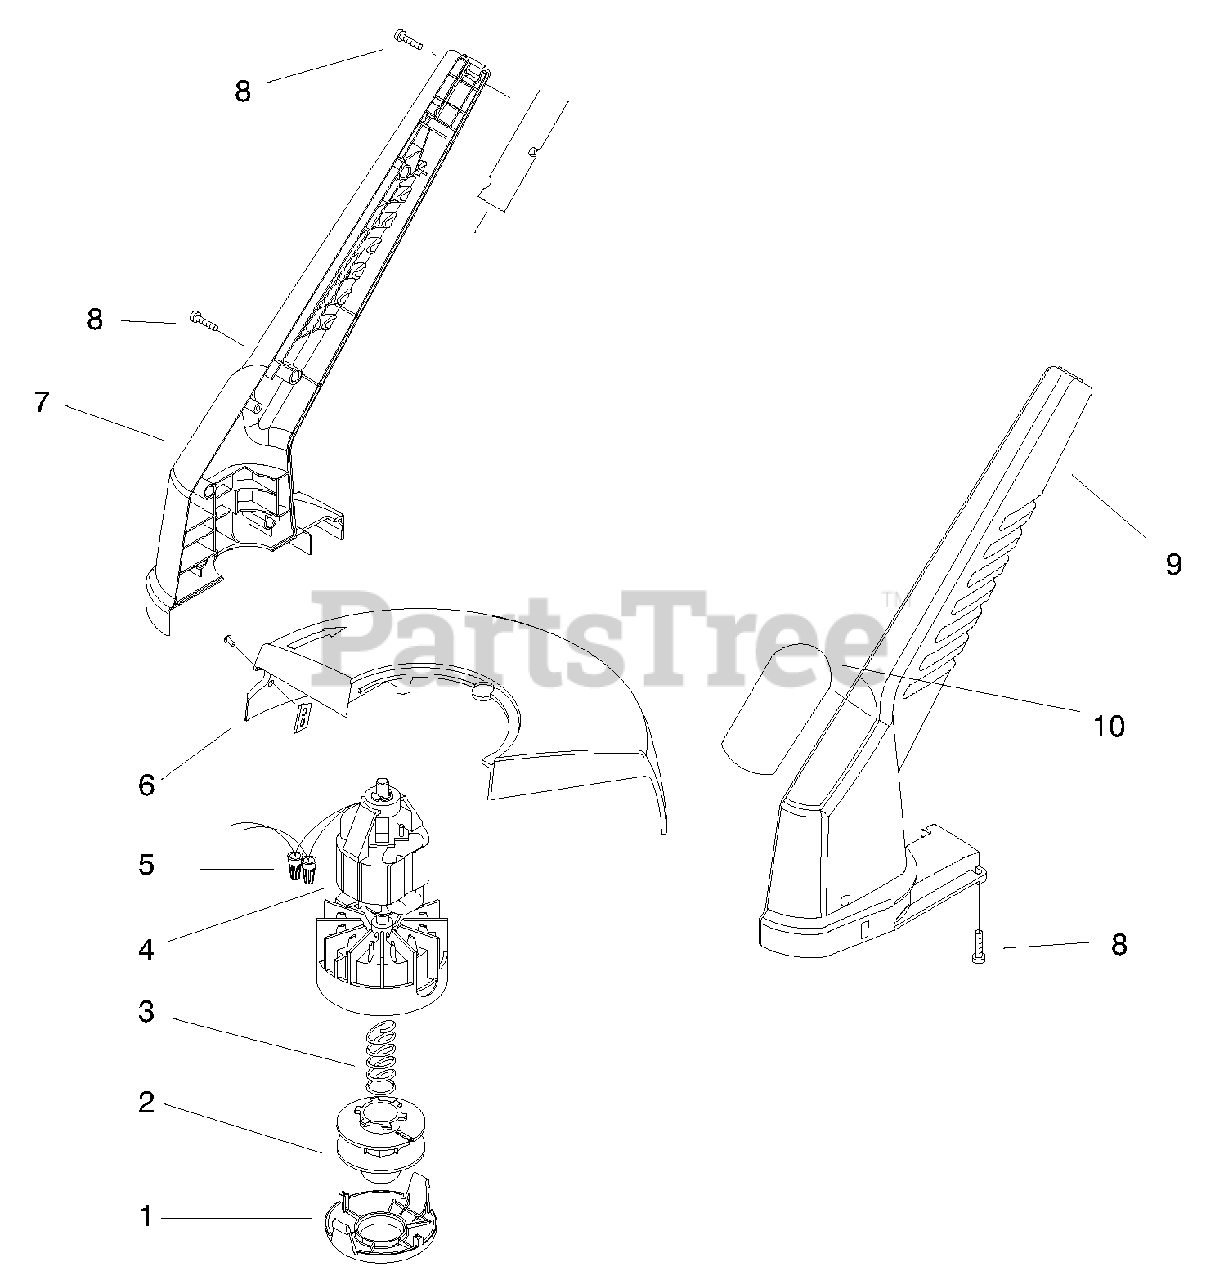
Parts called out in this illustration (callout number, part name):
4	Motor Assembly
5	Connector-Wire Nut
6	ASM-Shield-14"
7	Housing R.H.
8	Screw-Pan Hd.
9	Housing L.H.
10	Decal-14" Trimmer
